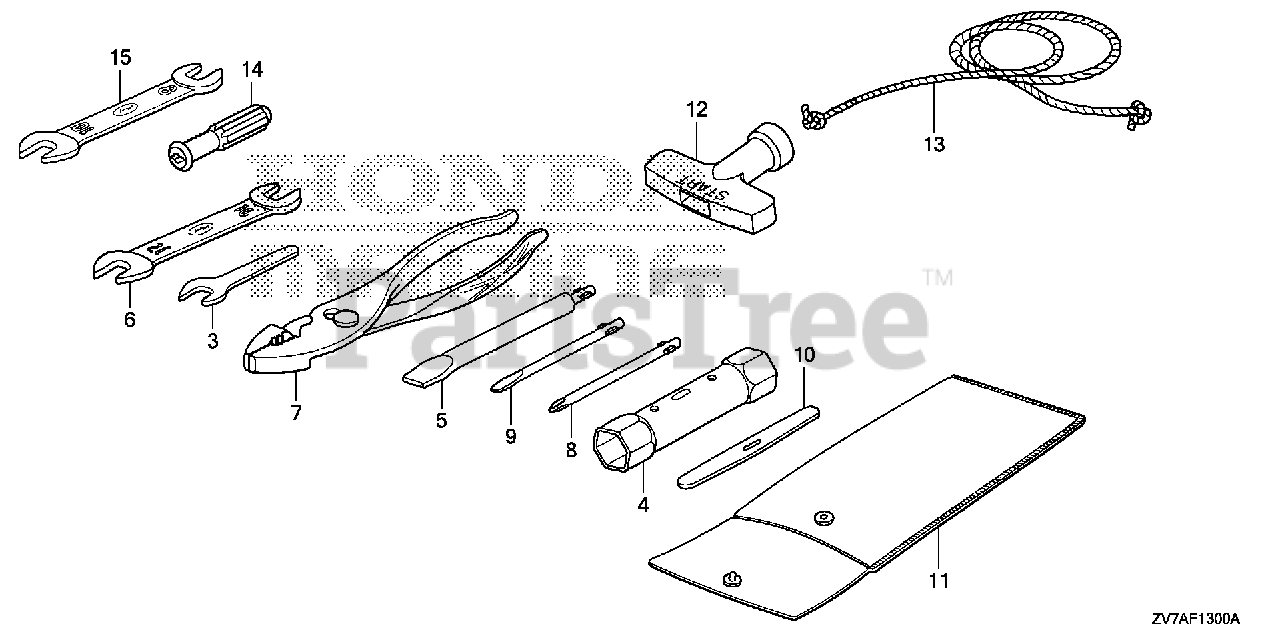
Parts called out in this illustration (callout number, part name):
4	WRENCH, BOX (P18X19)
5	SCREWDRIVER, CHECK BOLT
6	SPANNER (10X12)
7	PLIERS (135) (KOWA)
7	PLIERS (135)
8	DRIVER 1, PLUS SCREW (NO.2)
9	DRIVER 3, MINUS SCREW (NO.2)
10	LEVER
11	BAG, TOOL
11	BAG, TOOL (160MM)
12	KNOB, RECOIL SRARTER
13	ROPE, RECOIL STARTER (1300MM)
14	GRIP, SCREW DRIVER
15	SPANNER (8X10)
